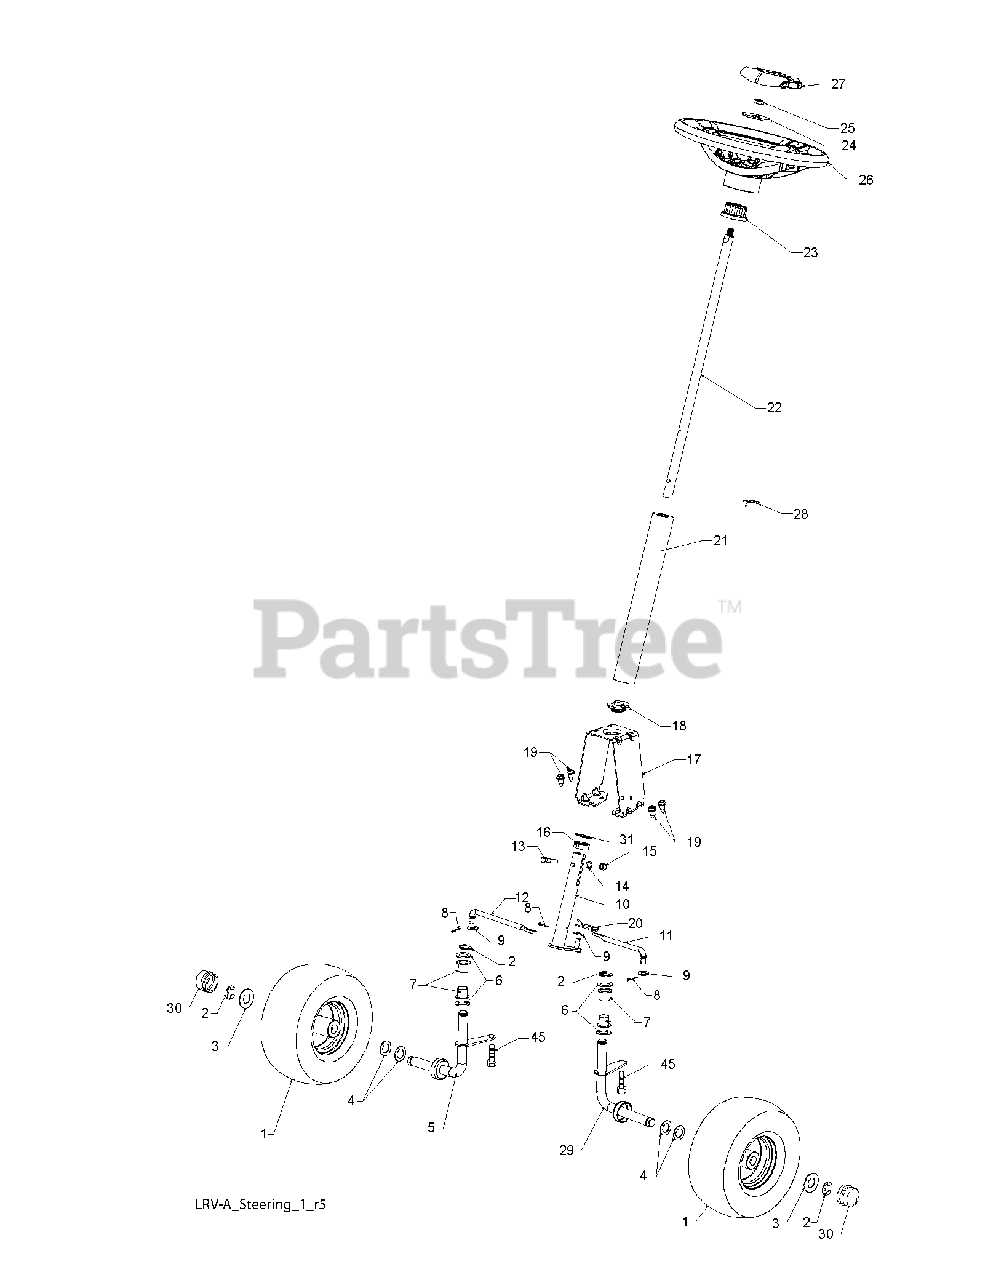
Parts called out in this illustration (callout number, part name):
1	WHEEL.ASM.FRONT.LRV.10" GRAY
2	E-RING LT
3	WASHER.HARDENED
5	SPINDLE.STEERING.RH.LRVA
7	Steering Column Bearing
8	PIN.COTTER.5/64X3/4
10	WELDMENT, LWR STRG SHAFT
11	LINK, STRNG LH LRV
12	LINK.STEERING.RH.LRV
13	HEX BOLT
15	NUT.71038.31-18.HEX.NYLOCK
16	BUSHING, STEERING SNAP
17	SUPPORT, UPPER STEERING
18	BUSHING,STEERING
19	SCREW
20	CLIP.SPRING.STEERINGG
21	FOAM.SHAFT.STEERING
22	SHAFT, STEERING
23	STEERING.WHEEL.ADAPTER
24	WASHER 9/16"ID, 2 3/8""OD
25	NUT.HEX.1/2-20
26	RP WHEEL.STEER.STDSRXX.GRAY
27	CAP, STEERING WHEEL
28	RETAINER.CLIP.SPRING.S
29	WELDMENT.SPINDLE.LH.LR
30	CAP.HUB.AXLE.LRVA/B
45	BOLT.SHOULDER.5/16-18X
